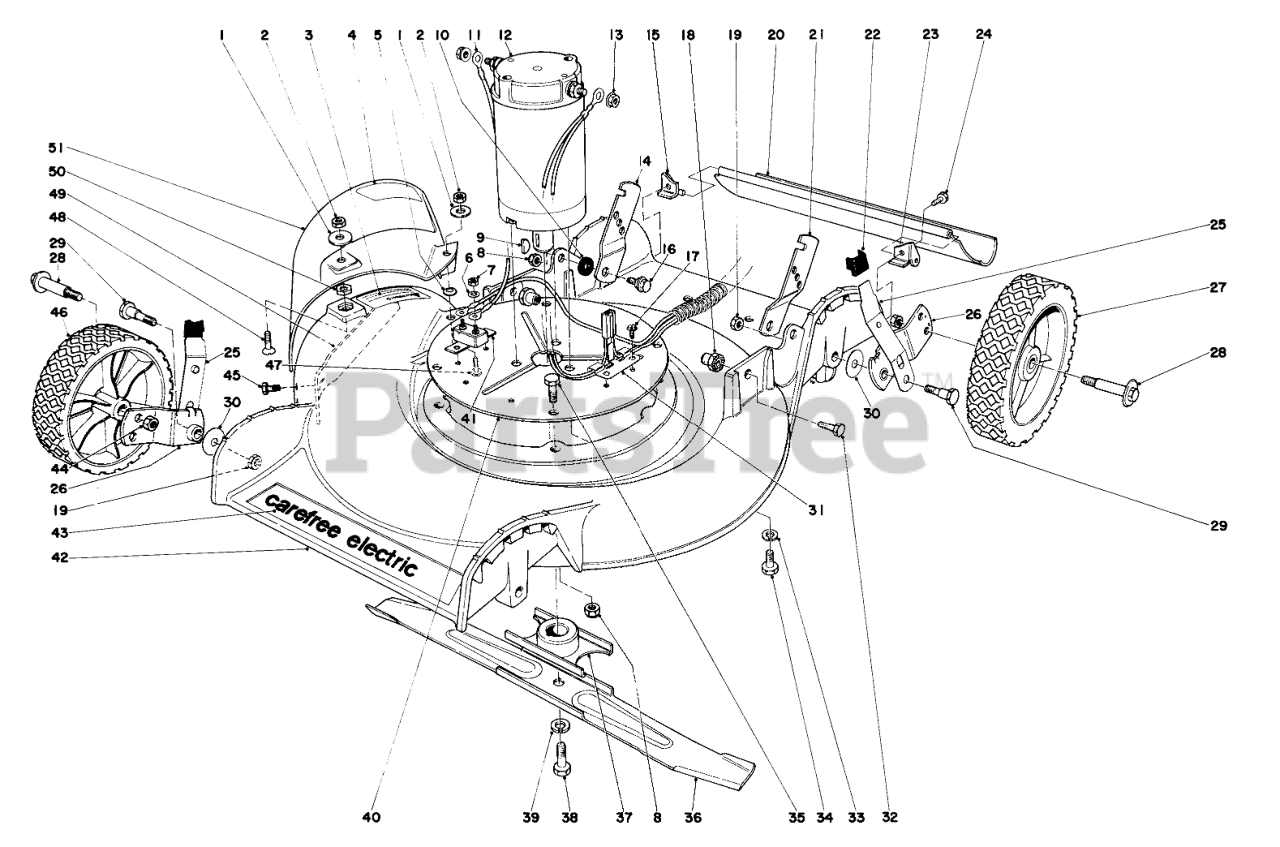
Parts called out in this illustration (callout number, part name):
1	WASHER-FLAT
2	NUT-JAM
3	Warning Decal
4	Decal
5	Push Nut
6	WASHER-LOCK, INT
7	NUT-HEX
8	NUT-HEX, SIDE DEFORM
9	KEY-WOODRUFF
10	SPACER
11	Lead Wire
12	Motor
13	Nut Belleville
14	Latch Handle R.H.
15	Pivot Bracket R.H.
16	SCREW-SHOULDER
17	SCREW-HWH
18	HANDLE PIVOT NUT
19	Nut
20	Rear Safety Shield
21	Latch Handle L.H.
22	Knob Arm
23	Pivot Bracket L.H.
24	SCREW-HWH
25	Spring Arm
26	Pivot Arm
27	WHEEL ASM 7
29	Pivot Bolt
30	WASHER-PIVOT
31	Support Connector
32	SCREW-HH
33	WASHER-LOCK
34	SCREW-HH
35	SCREW-HH
36	Blade
37	Blade Retainer
38	Capscrew
39	WASHER-LOCK
40	Plate Motor Mount
41	Circuit Breaker
42	Housing
43	Decal-Deck
44	Nut
45	SCREW-HWH
46	Wheel & Tire Assembly Front
47	Screw, Machine
48	Flat Head Screw
49	Deflector Bar
51	Deflector (Incl. Ref. #4)
